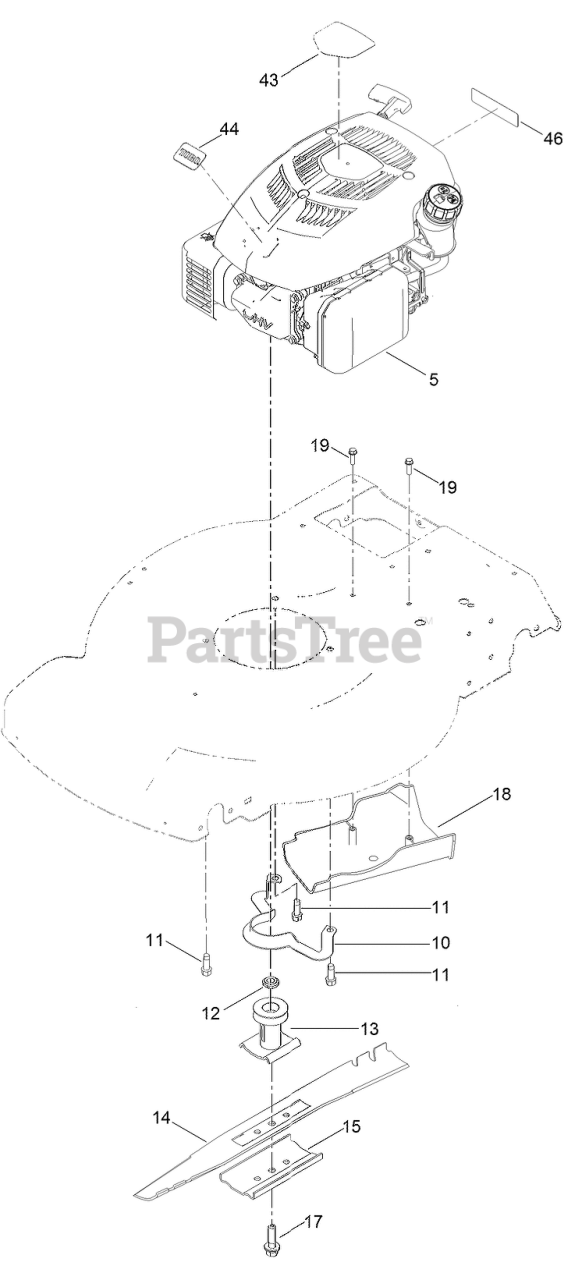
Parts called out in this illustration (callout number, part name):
5	ENGINE-1P65F-2
10	GUIDE-BELT
11	SCREW-TAPTITE
12	SPACER-DRIVER
13	DRIVER-BLADE
14	BLADE-22 INCH
15	SUPPORT-BLADE
17	BOLT-BLADE
18	COVER-BELT
19	SCREW-HWH
43	DECAL-SHROUD
46	DECAL-ARRESTOR, SPARK
